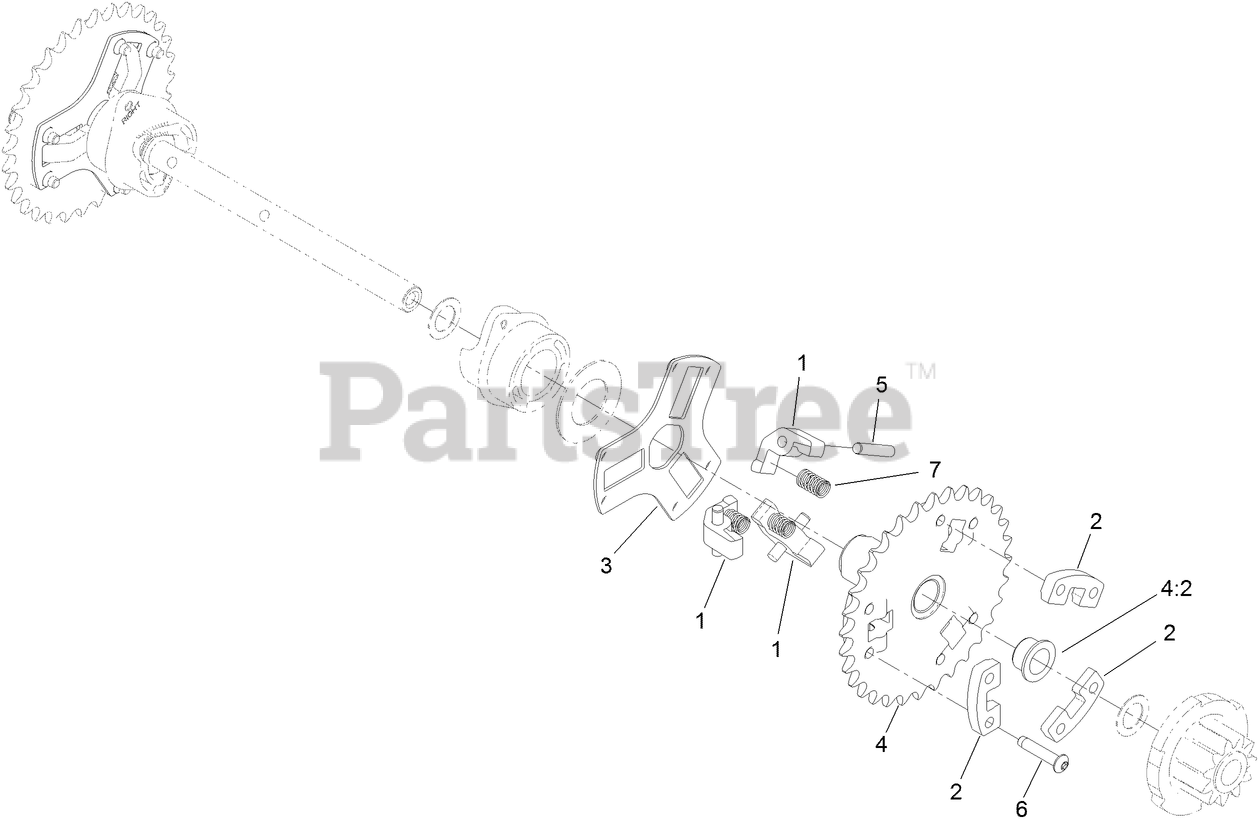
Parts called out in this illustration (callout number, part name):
1	PAWL-CLUTCH
2	SUPPORT-PAWL
3	RETAINER-PAWL, PIN
4	32T SPROCKET ASM
4:2	BUSHING-FLANGE
5	PIN-DOWEL
6	SCREW-TTH, THREAD ROLLING
7	SPRING-COMPRESSION
